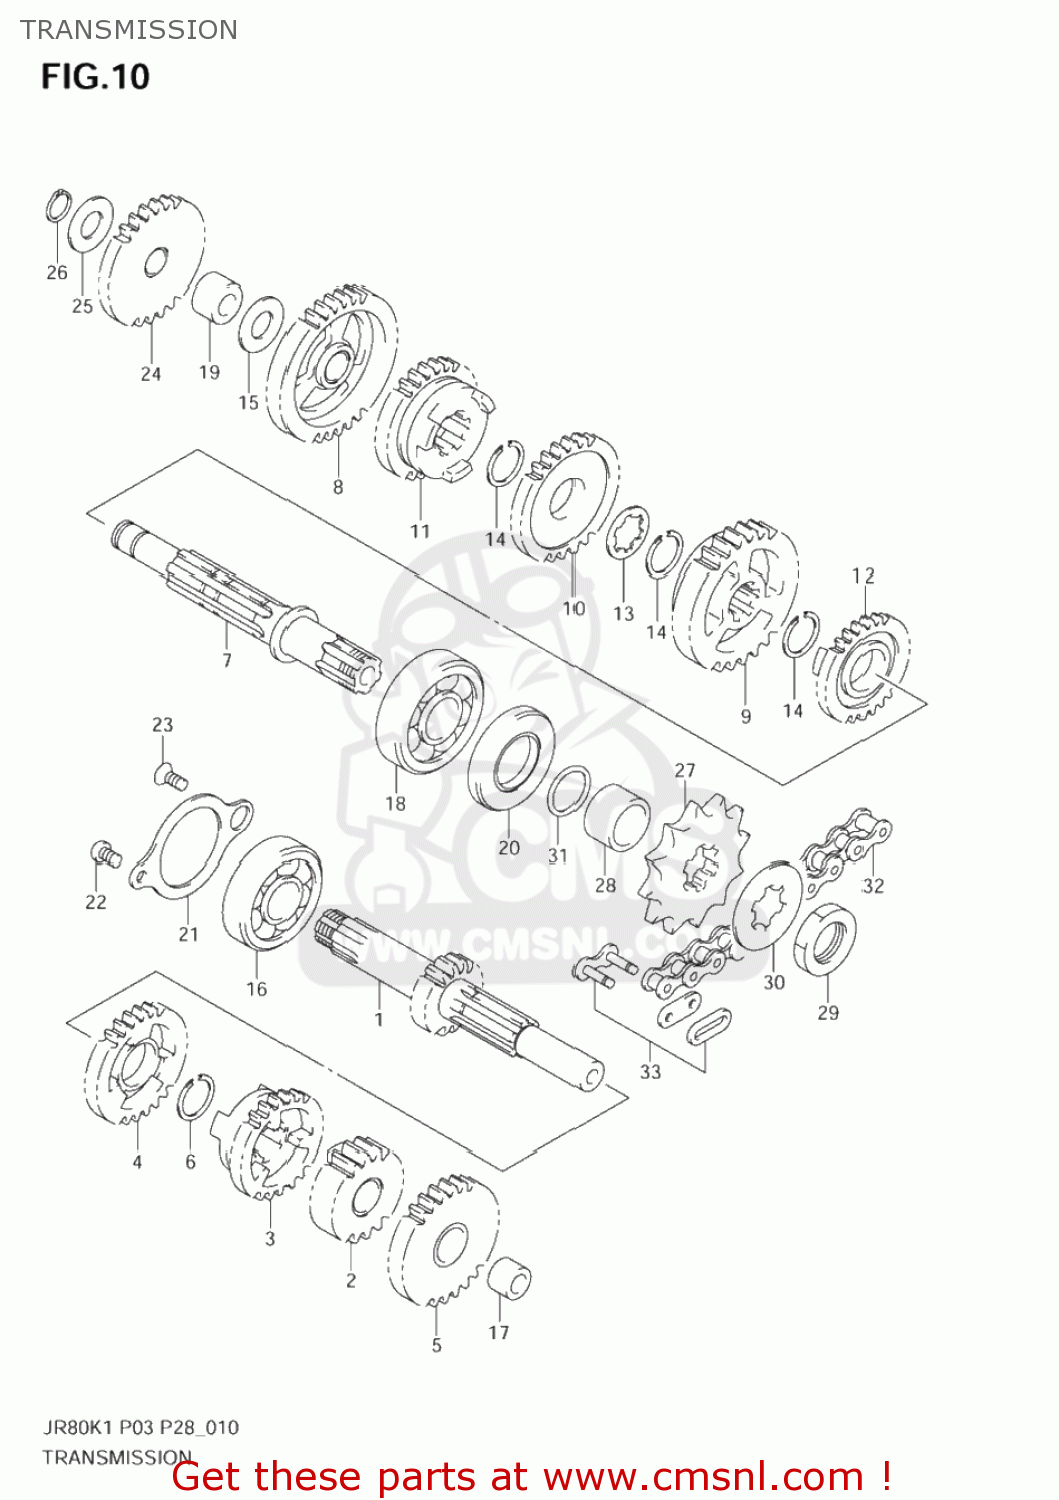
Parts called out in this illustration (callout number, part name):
1	SHAFT,COUNTER(NT:13)
2	GEAR,2ND DRIVE(NT:19)
3	GEAR,3RD DRIVE(NT:22)
4	GEAR,4TH DRIVE(NT:24)
5	GEAR,5TH DRIVE
6	CIRCLIP
7	SHAFT,DRIVE
8	GEAR,1ST DRIVEN(NT:35)
9	GEAR,2ND DRIVEN(NT:32)
10	GEAR,3RD DRIVEN(NT:29)
11	GEAR,4TH DRIVEN(NT:36)
12	GEAR,5TH DRIVEN(NT:24)
13	WASHER(13X24X1)
14	CIRCLIP
15	WASHER,LOCK
16	BEARING(17X40X12)
17	BUSH
18	BEARING
19	BUSH
20	SEAL,OIL(21X40X6)
21	RETAINER,CNTR SHAFT BEARING
22	SCREW
23	SCREW
24	GEAR,KICK STARTER IDLE
25	WASHER
26	CIRCLIP,12 MM
27	SPROCKET,ENGINE
28	SPACER(17X21X13)
29	NUT
30	WASHER,LOCK
31	O RING(D:1,ID:16.8)
32	CHAIN,DRIVE
33	JOINT,CHAIN
